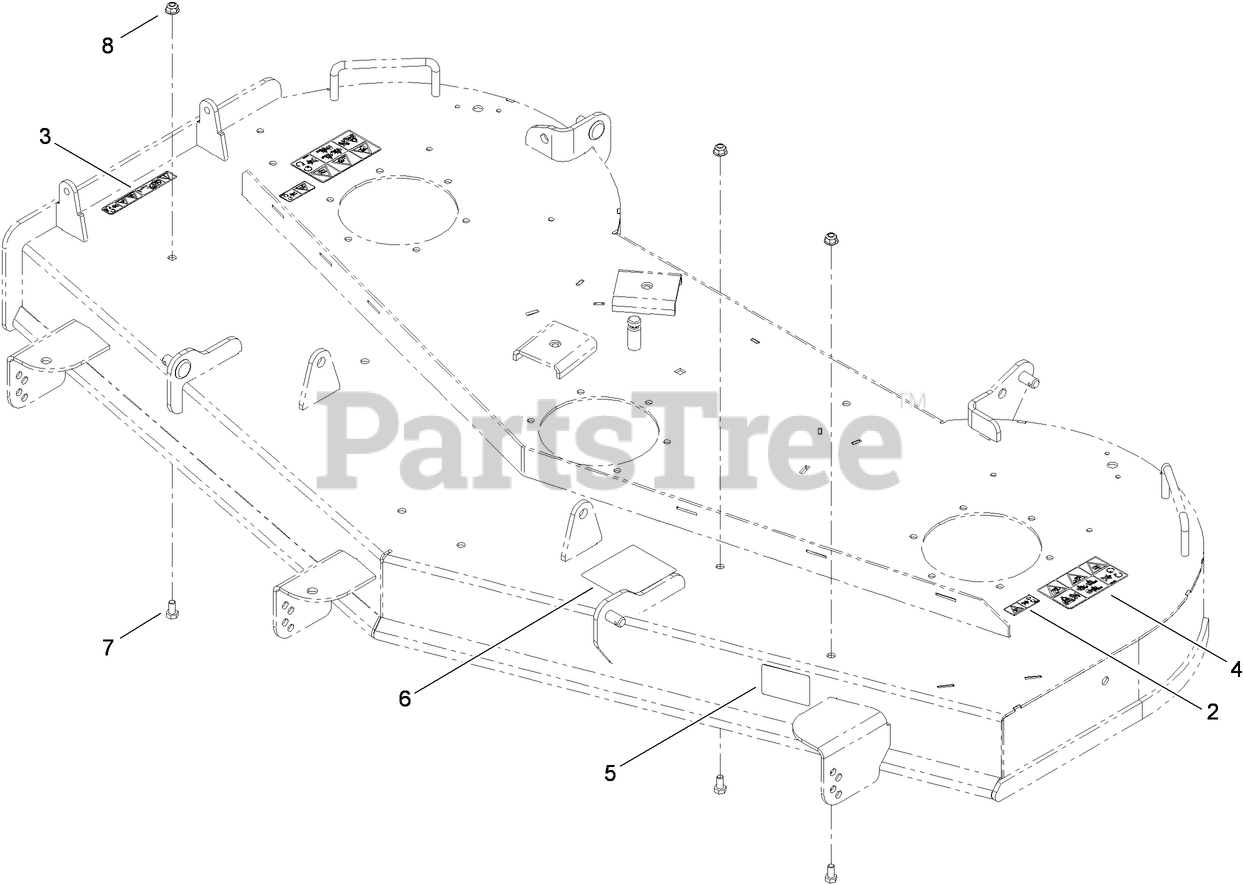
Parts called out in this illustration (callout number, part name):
2	DECAL-DANGER
3	DECAL-DANGER
4	DECAL-DANGER
5	DECAL-SCALP, ANTI
6	DECAL-ROUTING, BELT
7	SCREW-HH
8	NUT-HF, NI
